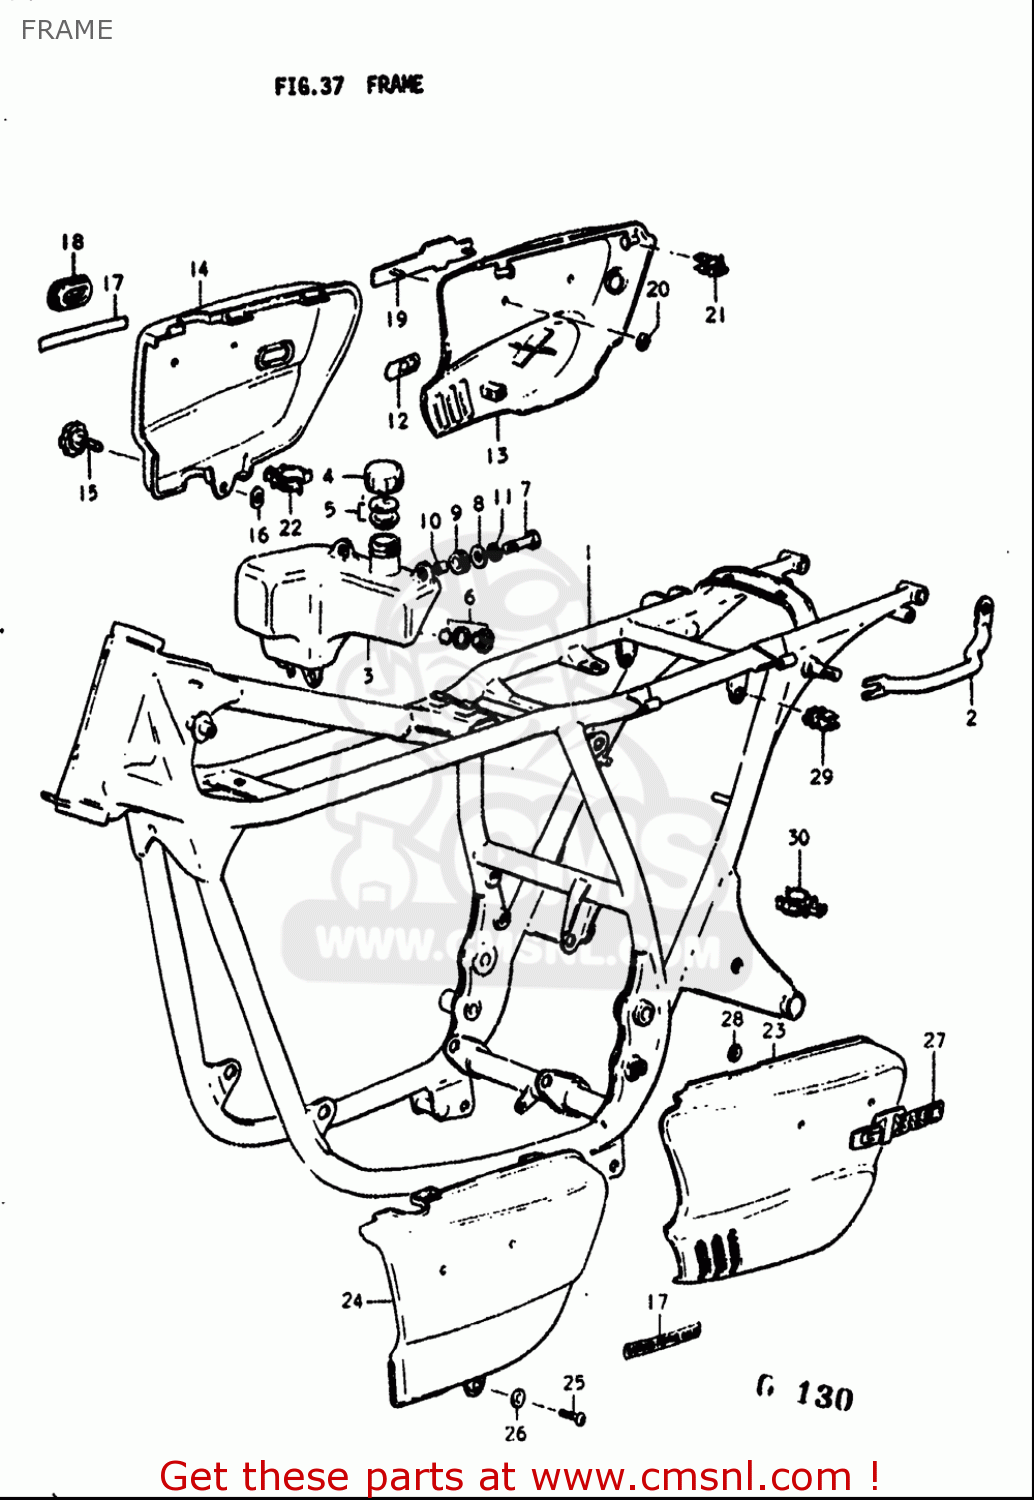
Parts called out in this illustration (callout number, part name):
4	CAP,OIL TANK
5	GASKET SET (NAS)
6	LENS SET,OIL LEVEL
7	BOLT
8	WASHER(6.5X18X1.6)
9	CUSHION
10	SPACER(6.5X10X10)
11	WASHER,LOCK
12	EMBLEM,CCIS
13	COVER,FRAME,R(BLACK)
14	COVER,FRAME,R
15	KNOB,FRAME COVER,R
16	NUT
19	EMBLEM,FRAME COVER,L
20	NUT
24	COVER,FRAME,L
26	WASHER
27	EMBLEM,FRAME COVER,L
28	NUT
